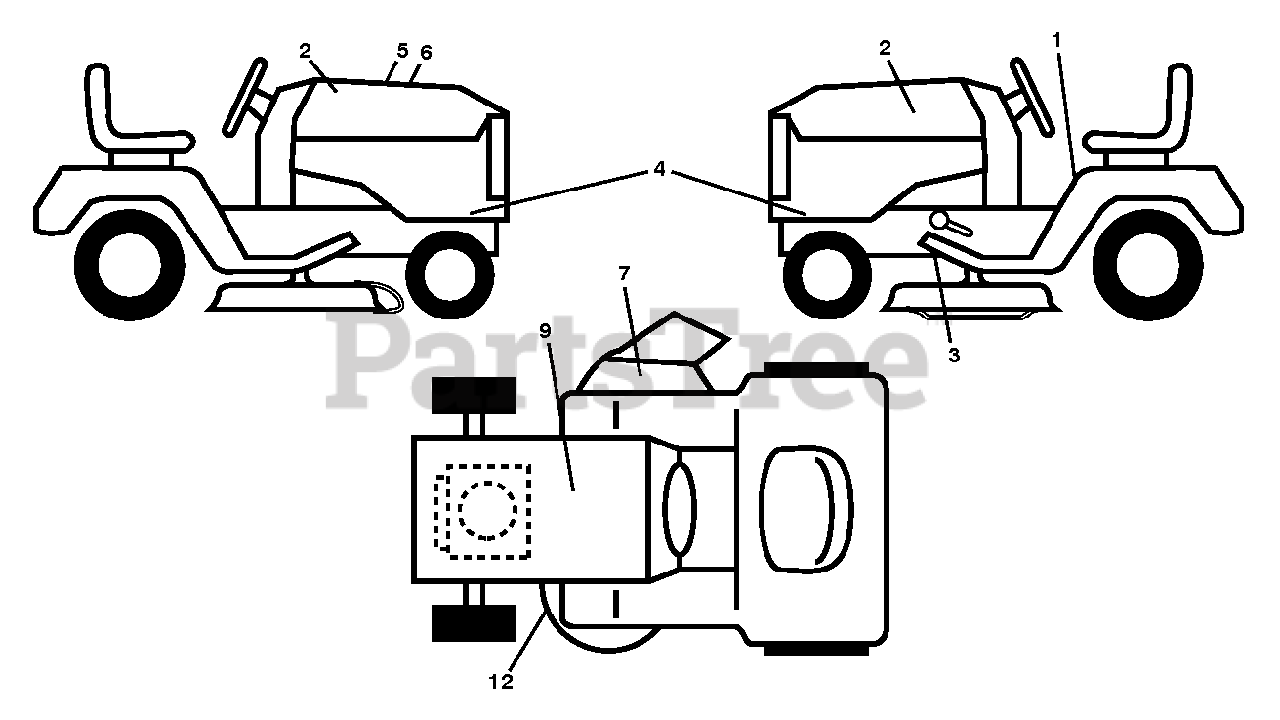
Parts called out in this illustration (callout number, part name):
1	DECAL.FENDER.WARNING.ENGLISH
2	DECAL.BADGE.170MM.TEXTLOGO.
3	DECAL.PEDAL.HUSQ.CROWN
4	DECAL HOOD PANEL
5	DECAL.WARNING.CUST.RESP.E85.
6	DECAL.RPL.KH.KT7.TLW.42E.K46
7	DECAL, DECK DEFLECTOR, WARNING
9	DECAL BTRY SYMBOLS
12	DECAL.V-BELT.SCH.42/46"MEC/ELE
